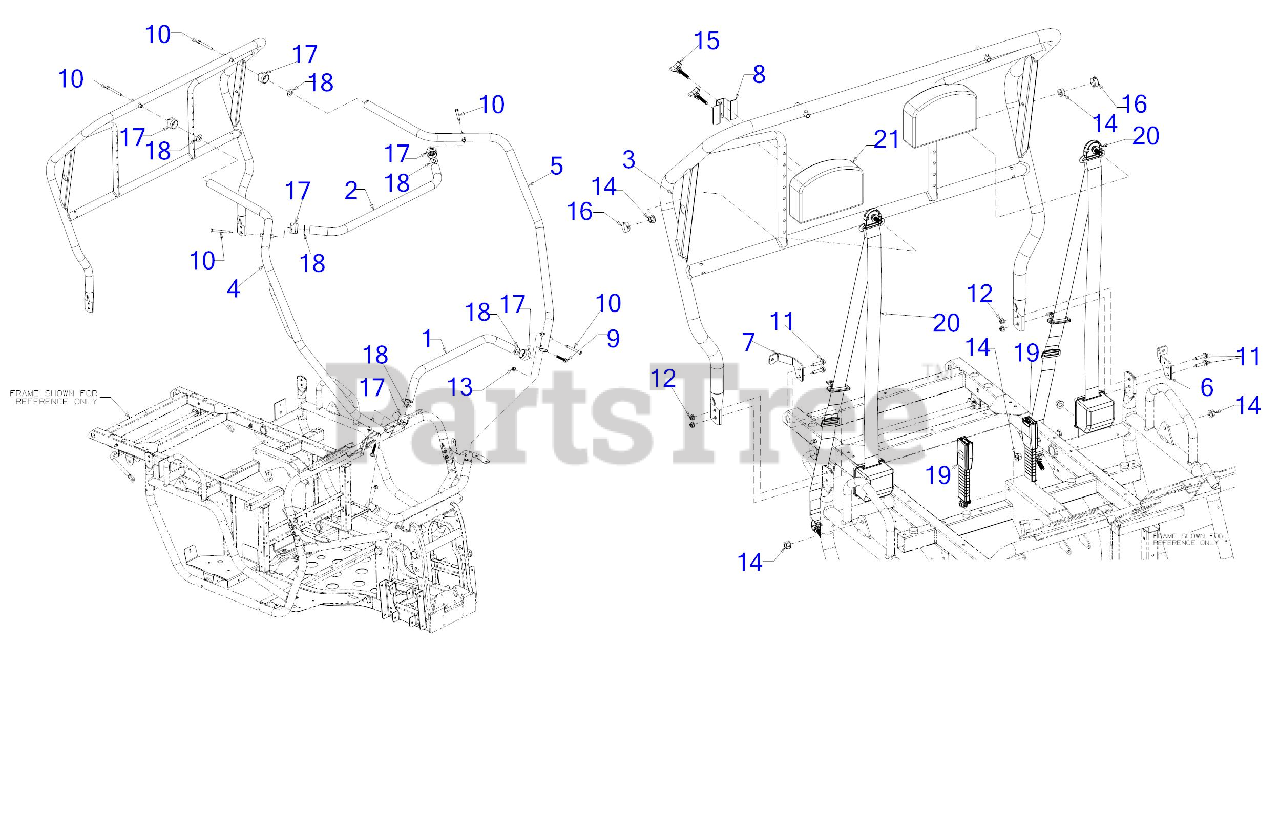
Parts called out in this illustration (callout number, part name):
9	SCREW 3/8-16 x 2.00 GR5
10	HEX CAP SCREW 3/8-16:3.25
11	SCREW 5/16-18 x 1.25 GR5
12	FLANGE LOCK NUT 5/16-18
14	FLANGE LOCK NUT
15	KNOB ASSEMBLY (5/16-18 x 2.00)
16	PANEL PLUG
17	TUBE COLLAR
18	FLAT WASHER .760ID X1.49OD x .06
19	3-POINT SEAT BELT
20	3-POINT SEAT BELT
21	HEADREST PAD
